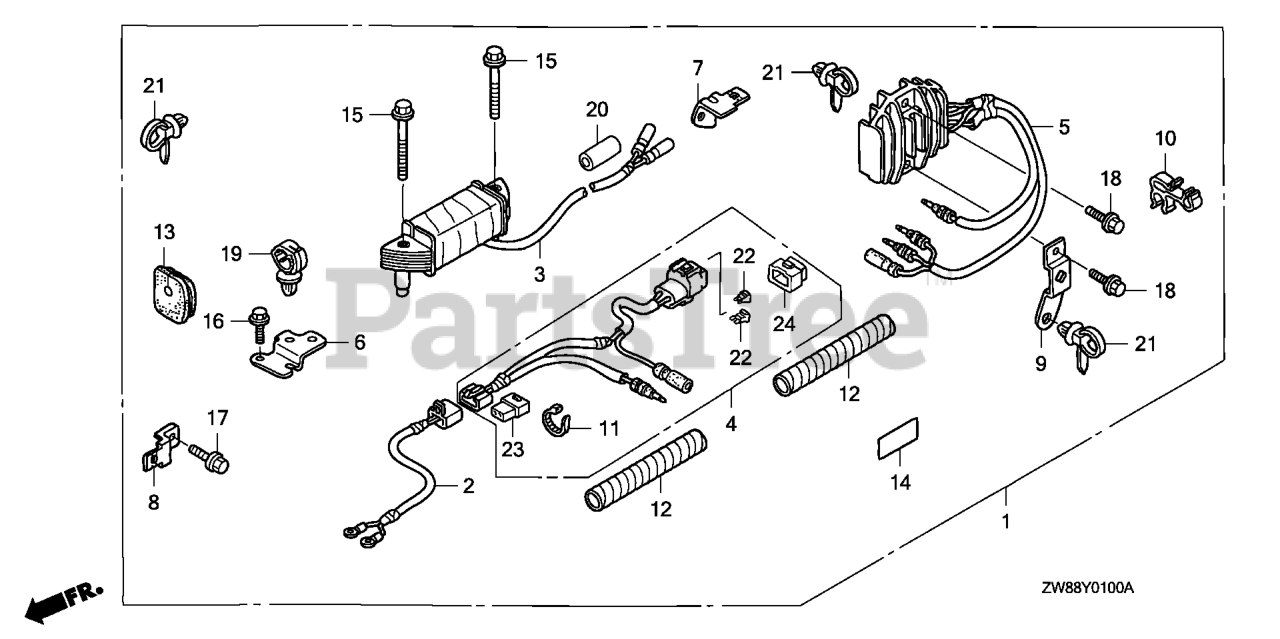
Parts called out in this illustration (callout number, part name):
1	COIL KIT, CHARGE (6A)
2	WIRE ASSY., BATTERY CHARGE
3	COIL ASSY., CHARGE (6A)
4	RECEPTACLE ASSY., CHARGE
5	RECTIFIER ASSY., REGULATOR
6	BRACKET, STARTER CABLE
7	BRACKET, FUSE CASE
8	BRACKET, CONNECTOR (D)
9	BRACKET, E-CLIP
10	CLAMP, DISTRIBUTOR WIRE
11	TIE, CABLE (NATURAL 2.4X92) Use up to Frame SN 1300359.
12	TUBE, SPIRAL A
13	GROMMET B, OIL CASE
14	MARK, RECEPTACLE (6A)
15	BOLT, FLANGE (6X52) (CT200)
16	BOLT, FLANGE (6X14) (CT200)
17	BOLT, FLANGE (6X12) Use from Frame SN 1005249.
18	BOLT, FLANGE (6X26) (CT200)
19	CLIP, HARNESS
20	TUBE, RUBBER (11.5X14.5)
21	CLIP, HARNESS BAND (151.5MM) (NATURAL)
22	FUSE, BLADE (20A)
23	CONNECTOR, DUMMY
24	COVER ASSY., FUSE (20A)
